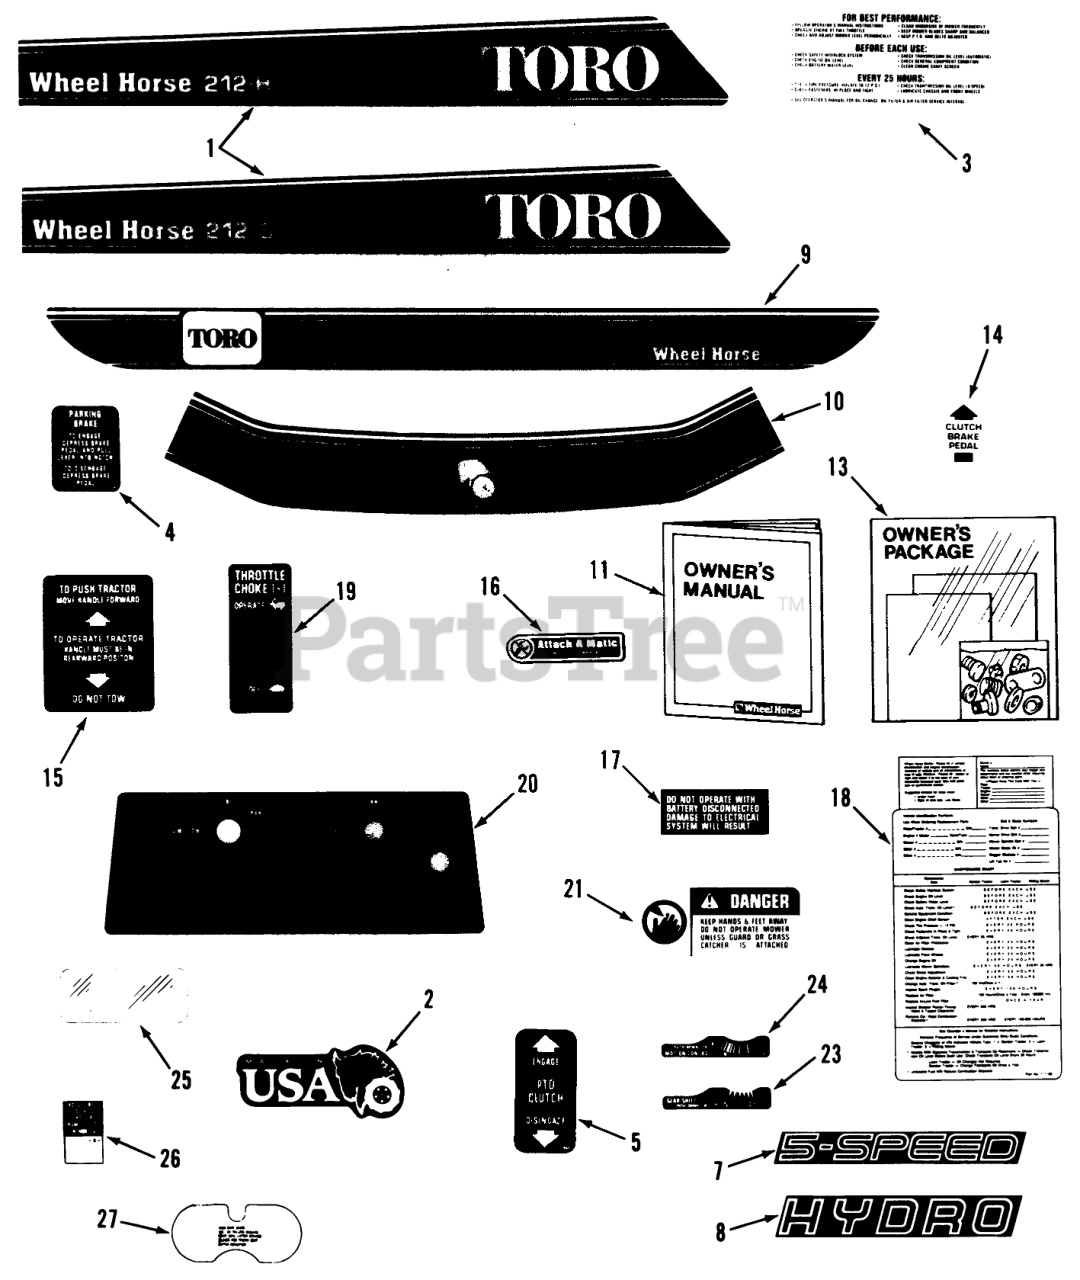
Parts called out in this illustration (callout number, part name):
1	DECAL-HOOD 212-5 R H
1	DECAL-HOOD 212-H R H
1	DECAL-HOOD 212-5 L H
1	DECAL-HOOD 212-H L H
2	Decal-Made In USA
3	Decal-Hood Rear
4	DECAL PARKING BRAKE
5	DECAL-PTO
7	DECAL-MODEL 5-SPEED
8	DECAL-MODEL HYDRO
9	DECAL-FENDER
10	DECAL-FRONT HOOD
13	Loose Parts Package (212-5)
13	Loose Parts Package (212-H)
14	DECAL CLUTCH & BRAKE
15	DECAL-PUSH
16	Decal-Attach-A-Matic
17	DECAL ELECT SYSTEM
18	MAINTENANCE-DECAL
19	DECAL-THROTTLE
20	DECAL-BACK PLATE
21	DECAL-DANGER
23	DECAL-SHIFT 5-SPEED
24	DECAL-MOTION CONTROL
25	DECAL-OVERLAY
26	DECAL-PTO BELT ADJ
27	DECAL-SEAT LIFTER
